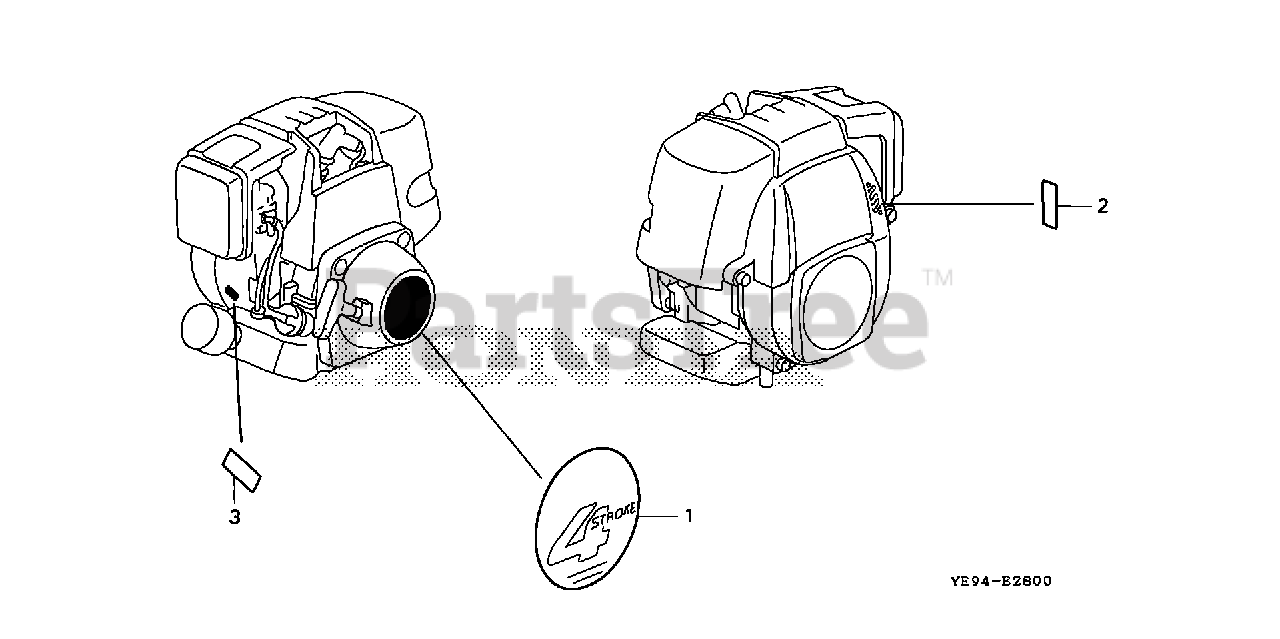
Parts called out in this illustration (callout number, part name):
1	EMBLEM (WX10)
2	MARK, THROTTLE INDICATION
3	MARK, TYPE (AY2)
